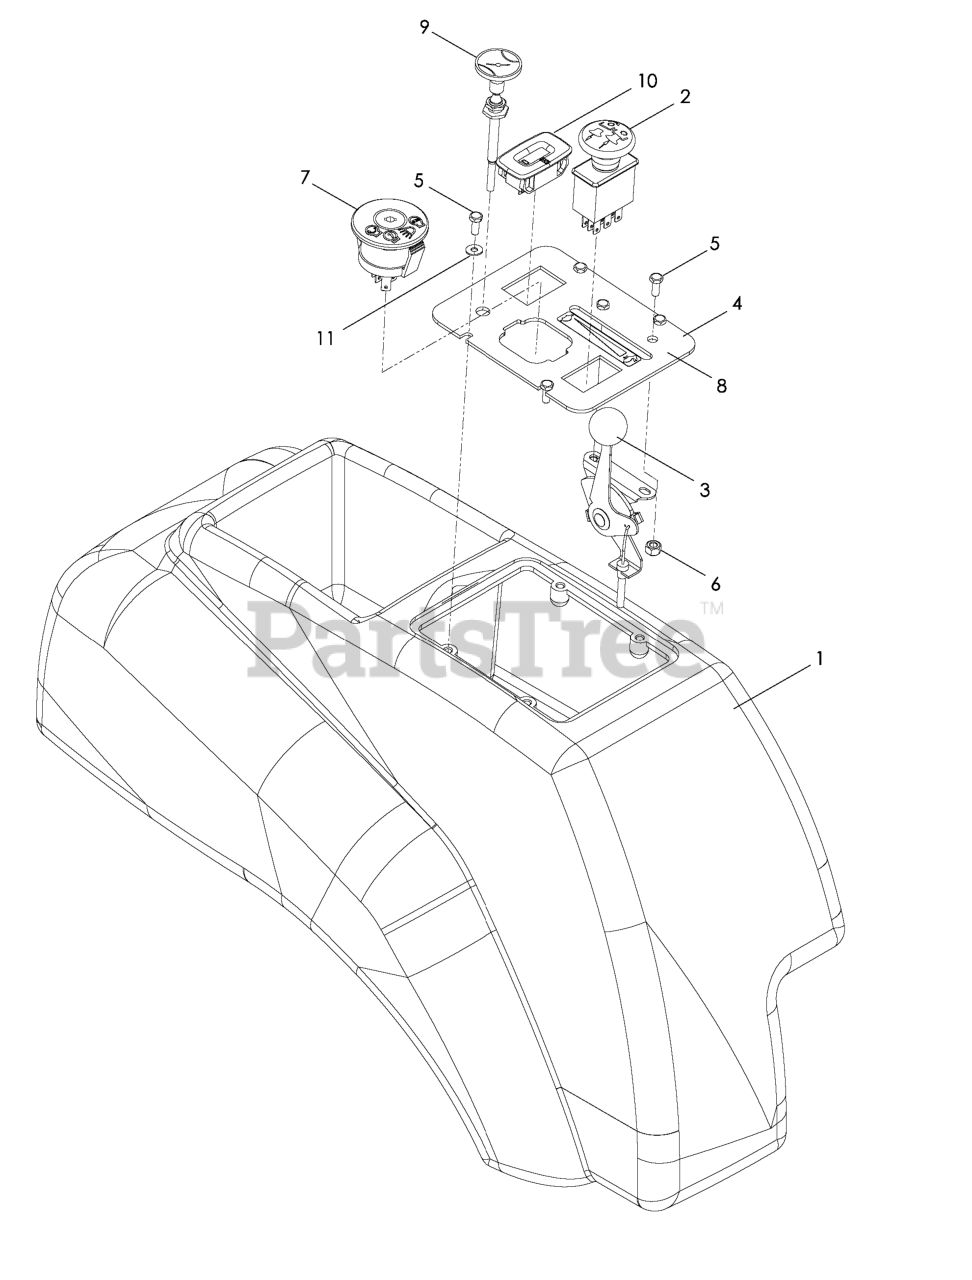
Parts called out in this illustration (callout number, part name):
1	FENDER CONSOLE
2	RP.SWITCH, BLADE
3	THROTTLE CABLE
4	CONSOLE PLATE, BLACK
5	HCS #10-24 X 1/2
6	NUT 10-24 NYLOC
7	RP IGNITION SWITCH
8	DECAL, THROTTLE
9	CHOKE CONTROL
10	HOUR METER
11	WASHER #10
